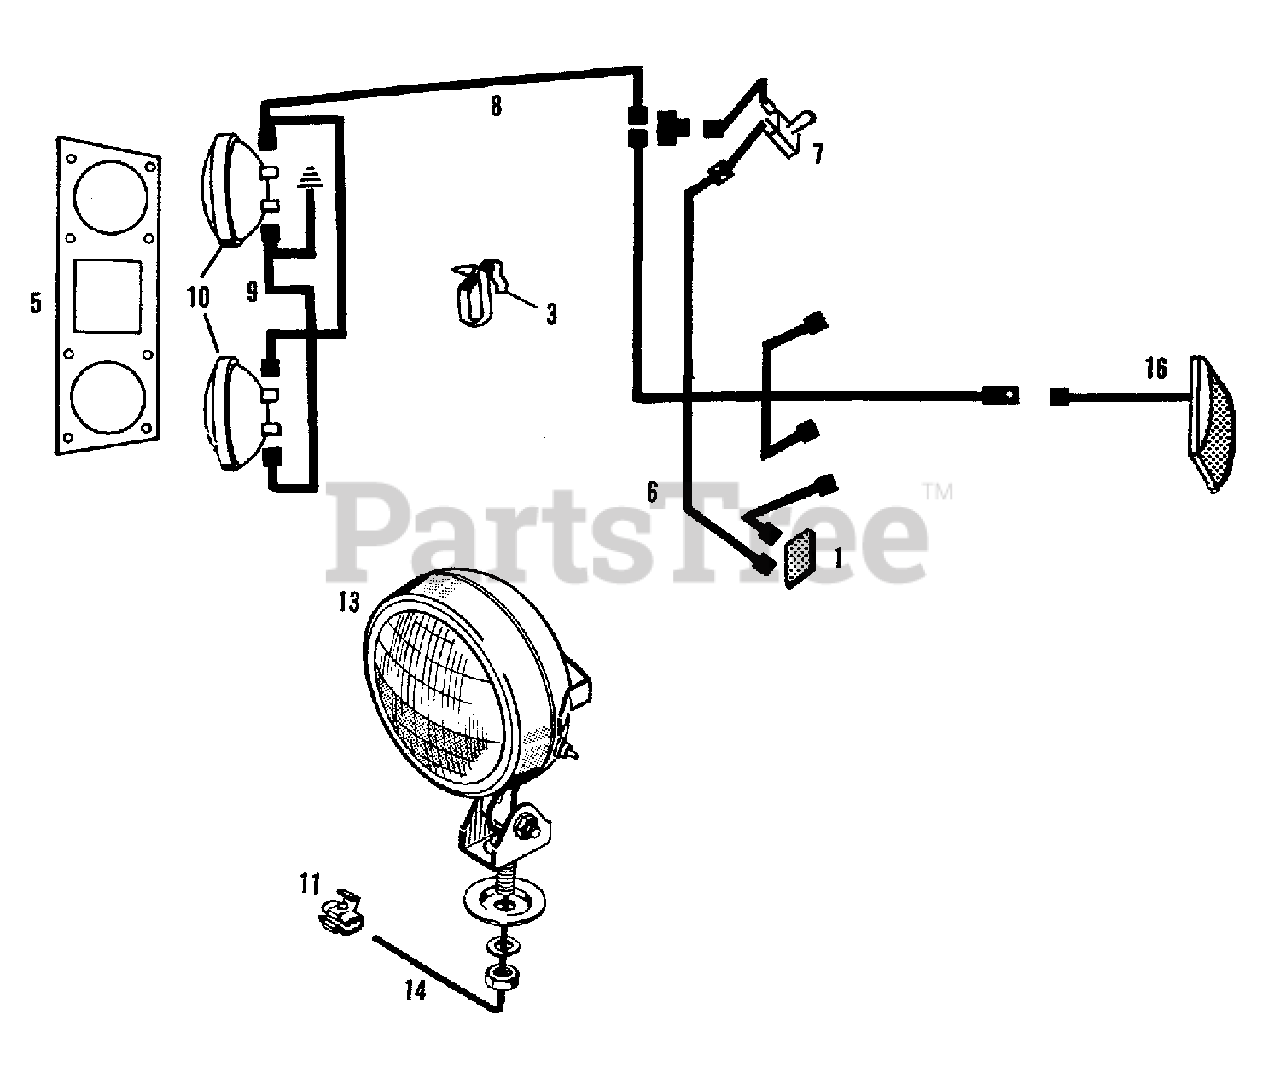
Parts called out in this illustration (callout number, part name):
1	STRIP, Buss Post
1	WASHER, Insulation
1	NUT, 1/4NC
1	WASHER, 9/32 x 5/8 x 1/16
1	LOCKWASHER, 1/4
2	BREAKER, Circuit
2	BOLT, 1/4NC x 1, Carriage
3	CLIP, Cable
4	CLIP, Speed
4	SCREW, #10NC x 1-1/4
4	NUT, #10NC
4	LOCKWASHER, #10
5	PANEL, Decal (Tractors Without Headlights)
5	PANEL, Decal (Tractors With Headlights)
6	LEAD, Wire (Buss Post To Light Switch)
7	SWITCH, Headlight
8	HARNESS, Headlight Wiring
9	HARNESS, Ground Wiring
10	LAMP, Seal Beam
10	BRACKET, Headlight Support
10	SCREW, #10NC x 3/8 Black Machine
10	LOCKWASHER, #10
10	NUT, #10NC
11	CONNECTOR, Self-Stripping
11	SCREW, #8NC x 1/2 Round Head Machine
12	TAPE, Foam (For Healight Retainers-Cut 4-4-1/2" Lengths)
13	LIGHT ASSEMBLY, Rear Work
13	LAMP ASSEMBLY, Seal Beam
14	LEAD, Wire
15	CONNECTOR, Self-Stripping
16	LAMP ASSEMBLY, Rear (Complete)
16	LENS, Red Plastic
16	NUT, #8NC
16	LOCKWASHER, #8
16	SCREW, #8NC x 1/2 Machine
